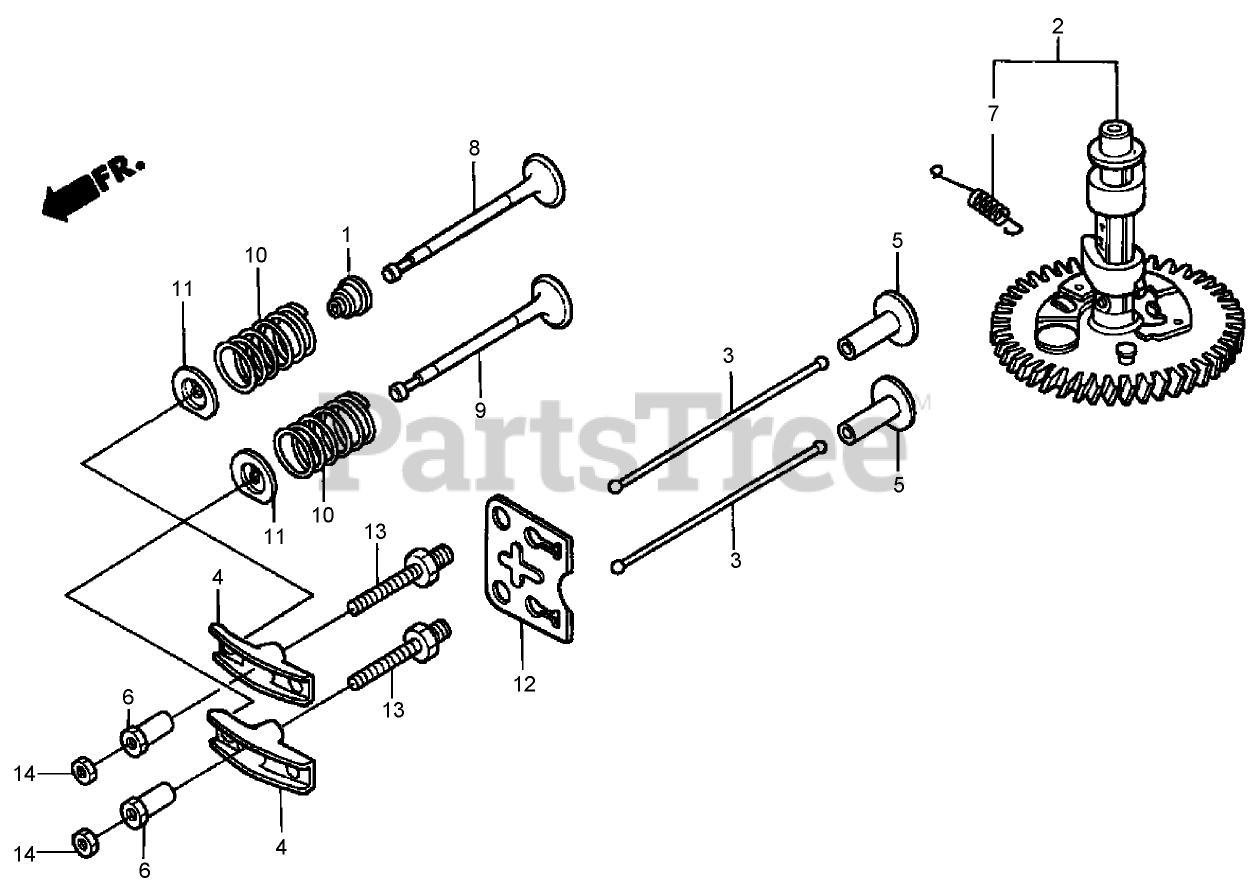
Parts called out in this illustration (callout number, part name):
1	SEAL-STEM, VALVE
2	CAMSHAFT ASM
3	ROD-PUSH
4	ARM-ROCKER, VALVE
5	Lifter-Valve
6	PIVOT-ARM, ROCKER
7	SPRING-RETURN, WEIGHT
8	VALVE-INTAKE
9	VALVE-EXHAUST
10	Spring-Valve
11	RETAINER-SPRING, VALVE (INTAKE)
12	Plate-GUIDE, Push Rod
13	BOLT-PIVOT (8 mm)
14	NUT-ADJUSTING, PIVOT
